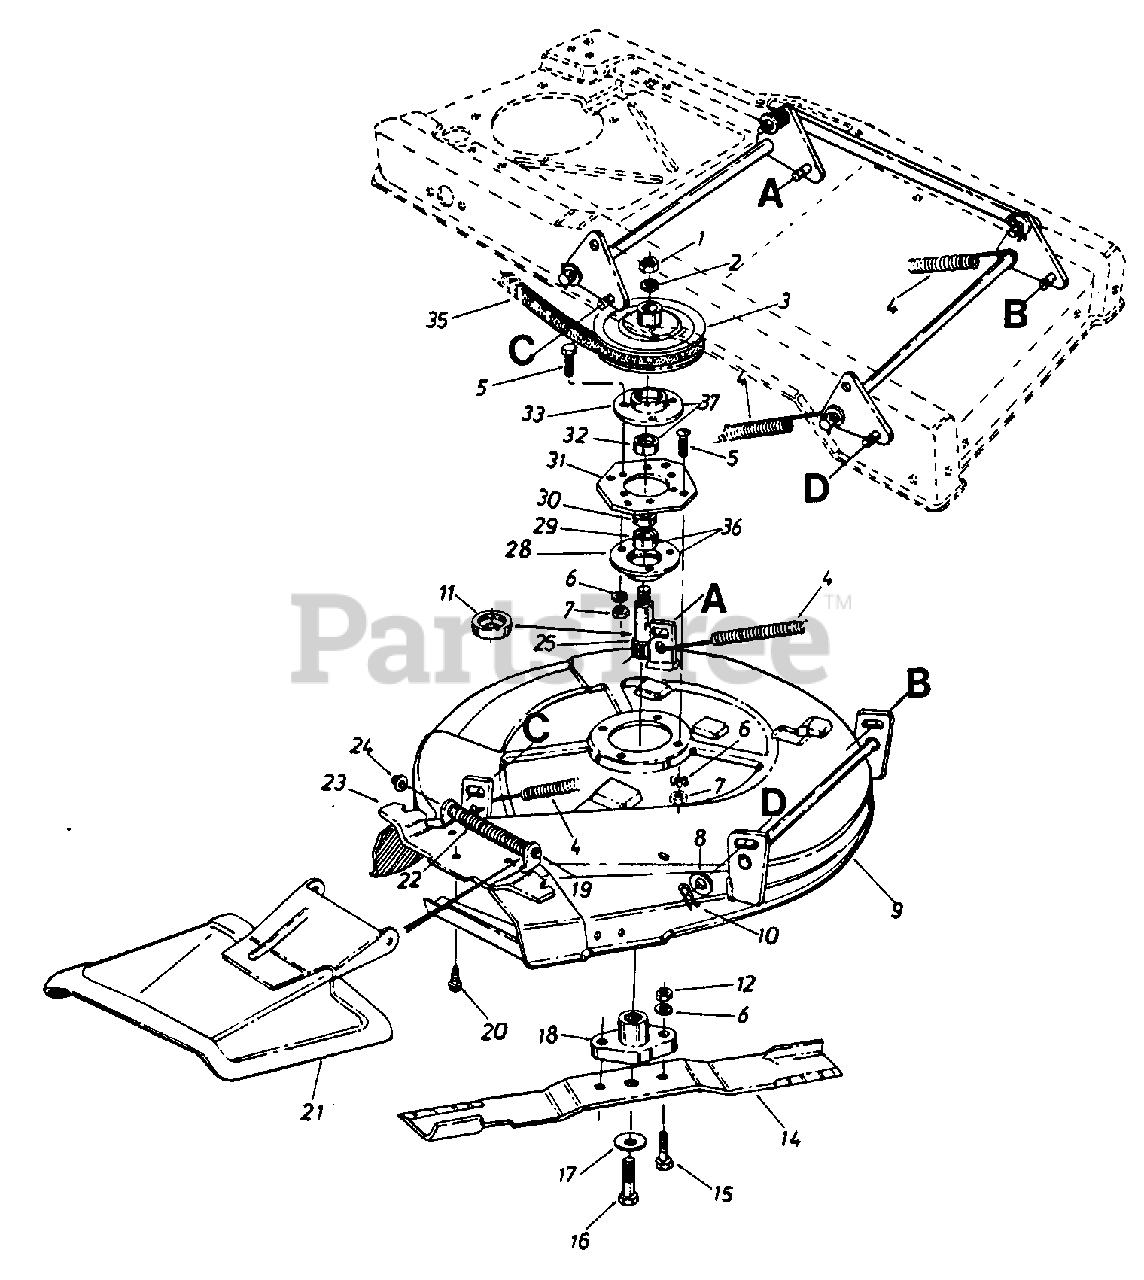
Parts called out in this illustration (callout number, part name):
1	NUT-HEX JAM 5/8-18
2	WASHER-BELL
4	SPRING-EXTENSION
5	SCREW-HEX 5/16-18 X .75
6	WASHER-LOCK-5/16
7	NUT-HEX 5/16-18
8	WASHER-FL .510 X .995 X .060
9	DECK ASSEMBLY-26IN
10	PIN-INTERN COT-1/2 DIA
11	SHIELD-BRG
12	NUT-5/16-24
14	BLADE-26IN
15	SCREW-HEX SPECIAL 5/16-24X1.0
16	BOLT-3/8 NF X 1"GR5
17	WASHER-BELL .390 ID X 1.375 X .062
18	ADAPTER-BLADE
19	PIN-HINGE
20	SCREW-HEX WASH SF TAPP
21	COVER-CHUTE-COMP
22	SPRING-TORSION
23	ADAPTER
25	SPINDLE-BLADE
28	HOUSING-BRG
29	BEARING-BALL
31	PLATE-SPINDLE MTG
32	BEARING-BALL
33	HOUSING-BRG
35	BELT-V 1/2 X 62
36	HOUSING ASSY-BRG
37	HOUSING ASSY-BRG
